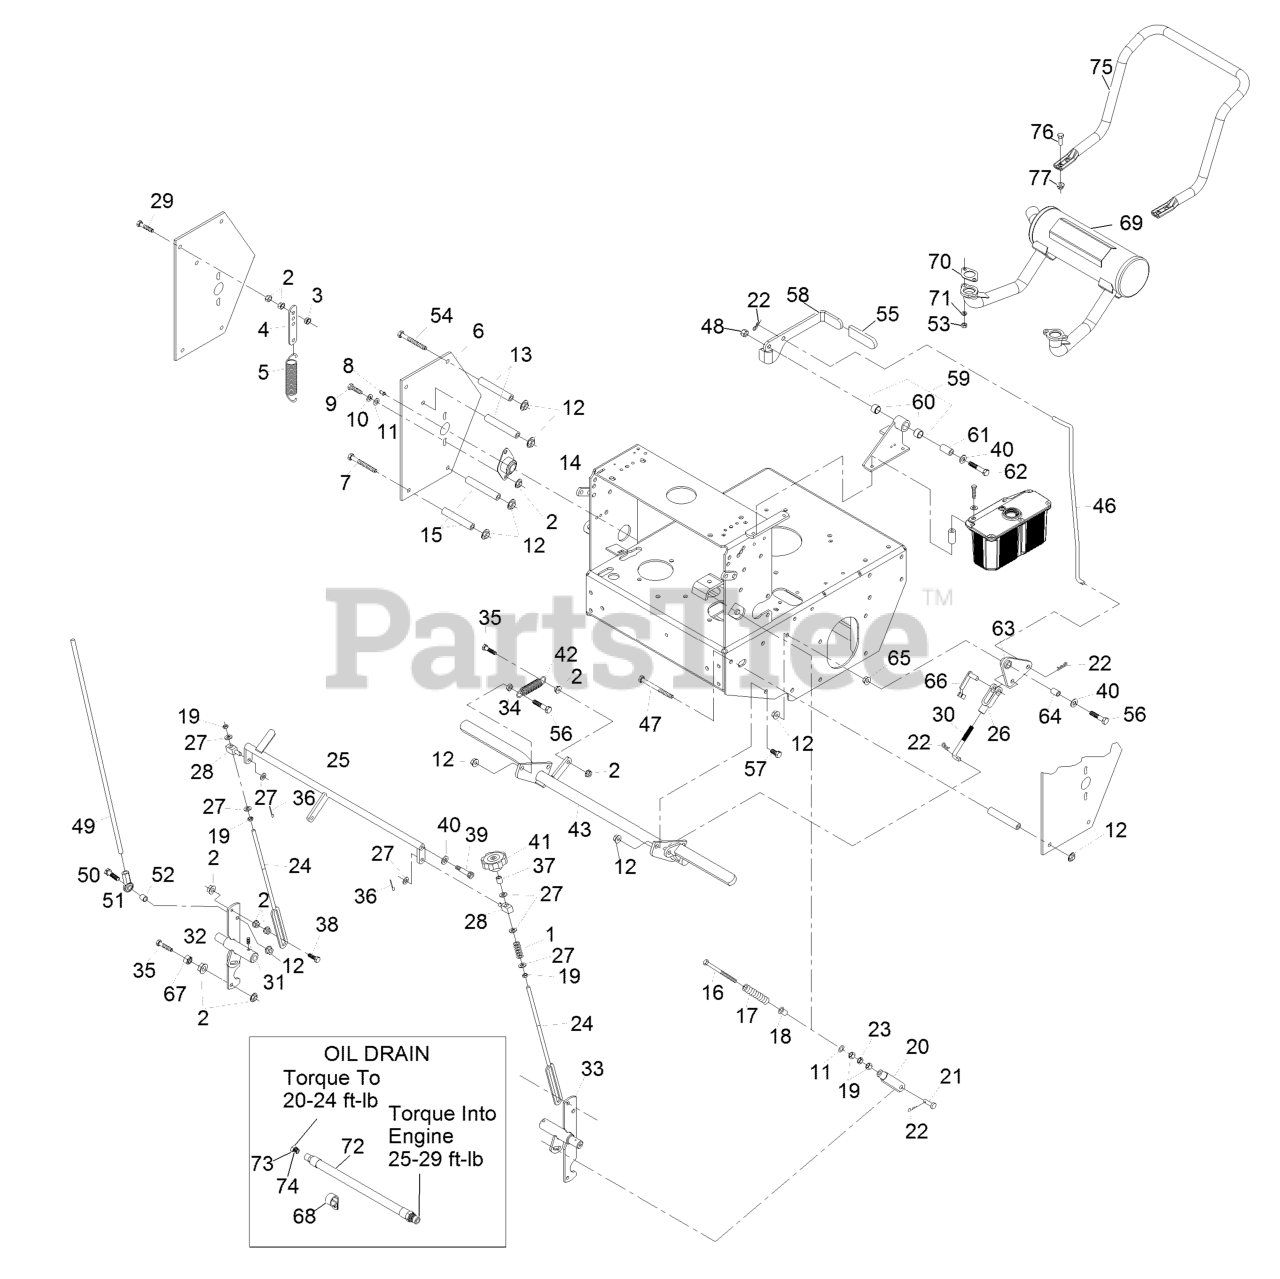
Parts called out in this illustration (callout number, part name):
1	SPRING-COMPRESSION
3	NUT-LOCK, NI
4	TAB-SPRING, EXTENSION
5	SPRING-EXTENSION
6	SHIELD-CONTROL
7	SCREW-HH
8	FITTING-GREASE
9	SCREW-HH
10	WASHER-LOCK
11	WASHER-FLAT
12	NUT-HHF, WHIZ
13	SPACER-SHIELD
14	BEARING-FLANGE, SIDE
15	SPACER-SHIELD
16	BOLT-RETURN, NEUTRAL
17	SPRING,COMPRESSION (NEUT)
18	BUSHING-FLANGED
19	NUT-HEX
20	YOKE-ADJUSTABLE
21	PIN-CLEVIS
22	PIN-COTTER
23	NUT-JAM
24	LINK-CONTROL, SPEED
25	CRANK-CONTROL, SPEED
26	YOKE-LINKAGE, BRAKE
27	WASHER-PLAIN
29	BOLT-TAP, HH
30	LINKAGE-LOWER
31	SCREW-SET
32	SHAFT-CONTROL, LH
33	SHAFT-CONTROL, RH
34	NUT-JAM
35	SCREW-HH, SPECIAL
36	PIN-COTTER
38	SCREW-HH
39	SCREW-HSH
40	WASHER-FLAT
41	KNOB-TRACKING
42	SPRING-IDLER
46	LINKAGE,UPPER- TTHP
47	SCREW-HH
48	NUT-LOCK, NI
49	LINK,DRIVE (PLTD)
50	SCREW-HH
51	JOINT-BALL END, LH
52	SPACER-TUBE, PUMP LINK
54	SCREW-HH
55	GRIP-LEVER
56	SCREW-HH
57	SCREW-HH
58	LEVER,PARK BRK W/DECAL
59	BRACKET ASM
60	SLEEVE-BUSHING
61	BUSHING-PIVOT
62	SCREW-HH
63	BELLCRANK ASM
64	BUSHING-PLASTIC
66	PIN-SPRING, CLEVIS
67	NUT-JAM
68	CLIP-LOOM
69	MUFFLER-HORIZONTAL
70	GASKET-EXHAUST
71	WASHER-LOCK
72	ASM, ENGINE OIL DRAIN HOS
73	PLUG-HH
74	O-RING
75	GUARD-MUFFLER
76	SCREW-HH
77	NUT-HF, NI
